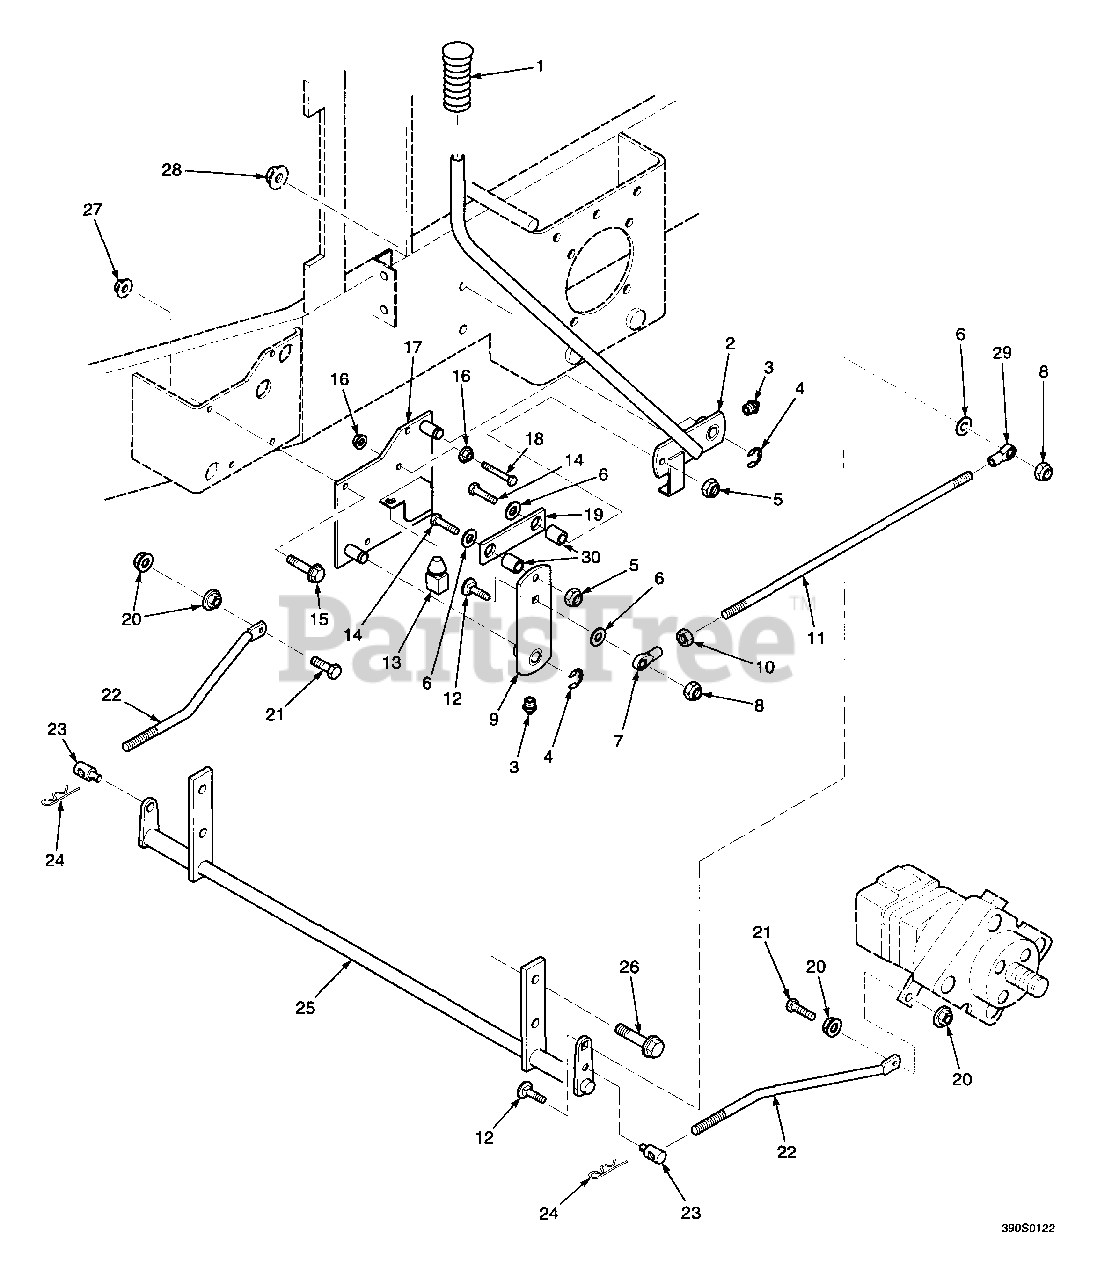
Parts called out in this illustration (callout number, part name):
1	Grip, Handle
2	Lever, Brake
3	Grease Fitting
4	Retaining Ring, .625 Ext
5	Hex Locknut, Elastic Stop, 3/8-16
6	Washer, Flat, 3/8 (.391 x .938 x .105)
7	Ball Joint, 3/8-24 RH Thd
8	Hex Locknut, Elastic Stop, 3/8-16
9	Arm, Weldment
10	Hex Nut, 3/8-24
11	Rod, Parking Brake
12	Carriage Bolt, 3/8-16 x 1-1/2
13	Switch, Interlock
14	Bolt, Hex Head, 3/8-16 x 1.00
15	Serr. Fl. Hex Head Capscrew, 5/16-18 x 1.00
16	Serr. Fl. Hex Nut, 3/8-16
17	Mounting Base, Parking Brake
18	Bolt, Hex head, 3/8-16 x 1-1/4
19	Link, Cam
20	Serr. Fl. Hex Nut, 1/4-20
21	Bolt, Hex Head, 1/4-20 x 1-1/4
22	Rod, Brake Actuator
23	Swivel
24	Hair Pin, Cotter, .08 x 1.19
25	Actuator, Brake
26	Serr. Fl. Hex Head Capscrew, 1/2-13 x 1-3/4
27	Serr. Fl. Hex Nut, 5/16-18
28	Serr. Fl. Hex Nut, 1/2-13
29	Ball Joint, 3/8-24 LH Thread
30	Sleeve
